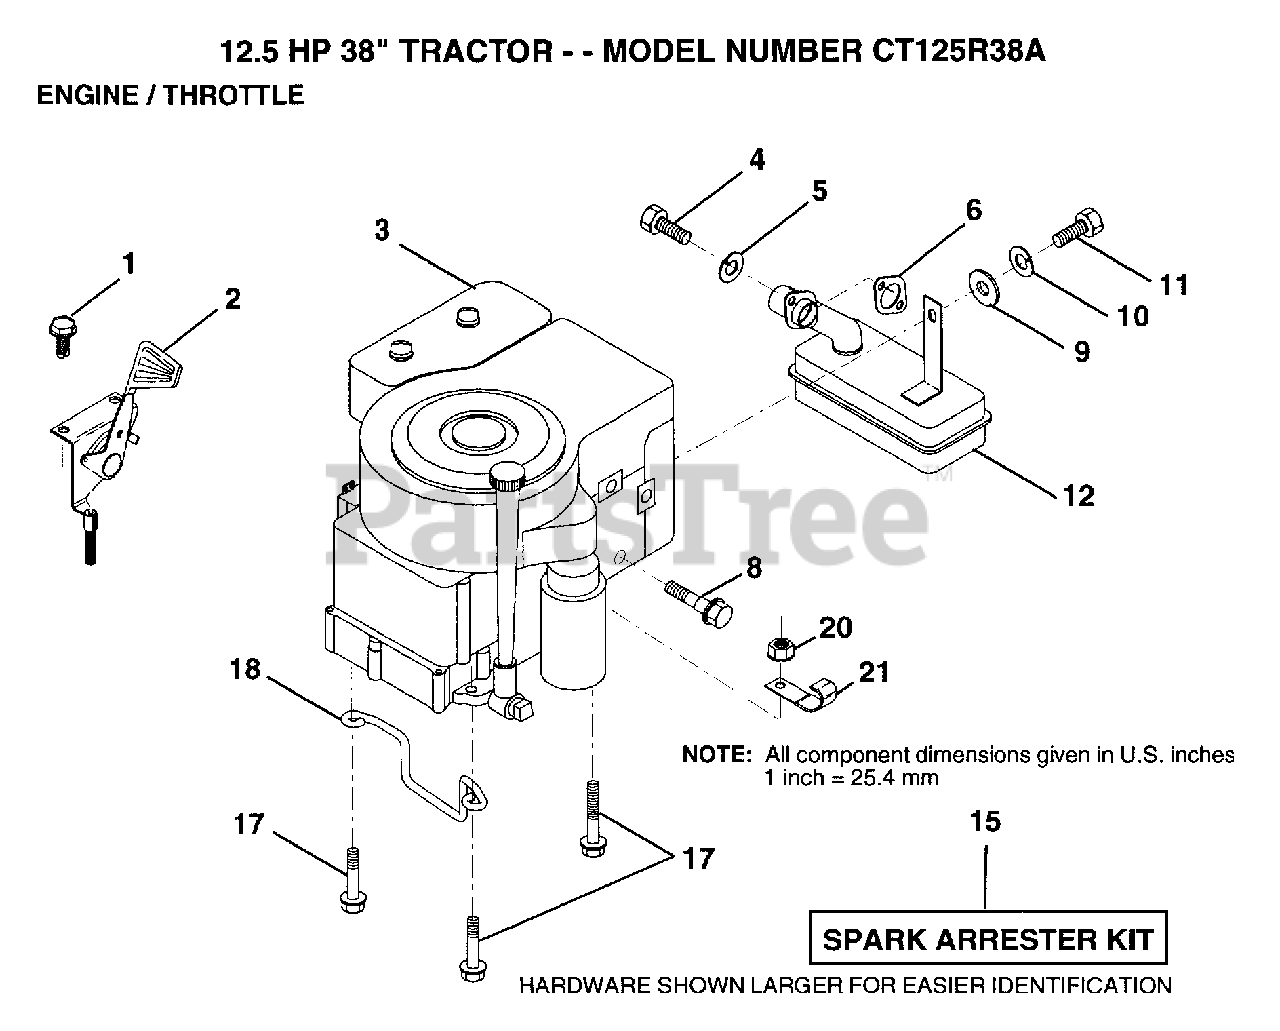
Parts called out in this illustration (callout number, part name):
1	SCREW
2	THROTTLE CONTROL
4	SCREW
5	LOCKWASHER
8	BOLT T
10	LOCKWASHER
12	MUFFLER
17	SCREW LT
18	"KEEPER,DR BELT GR"
20	NUT
21	CLIP T
